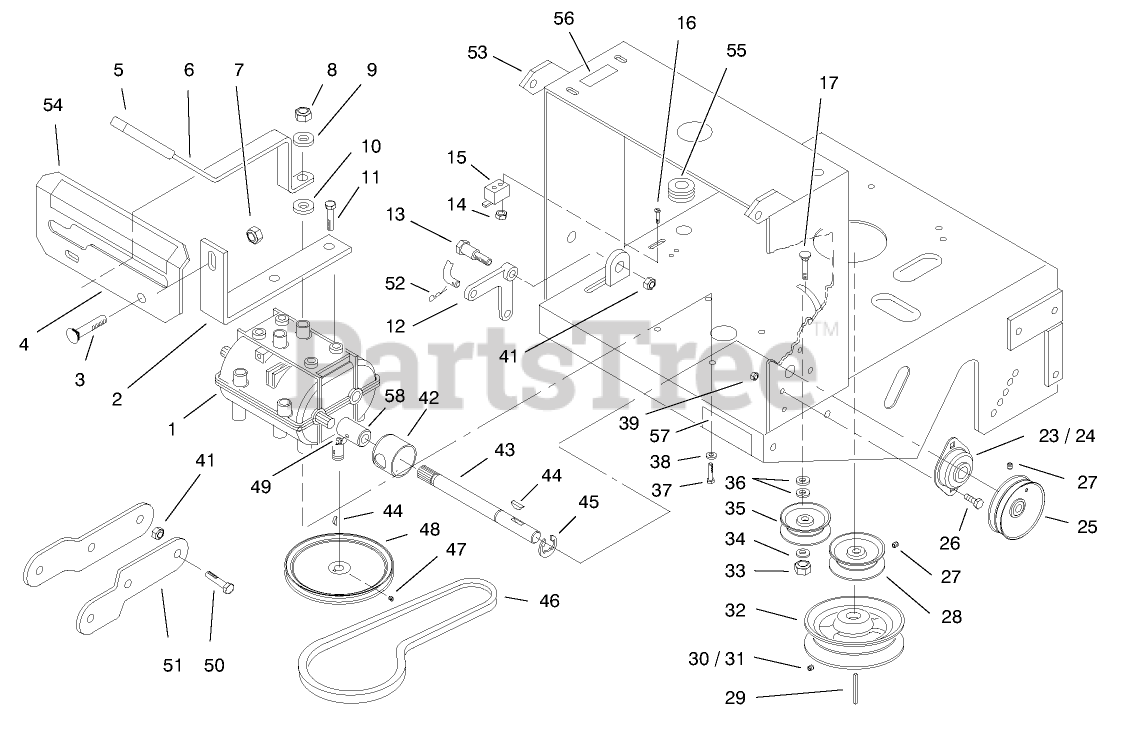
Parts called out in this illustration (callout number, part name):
1	Transmission-Peerless Model No. 700-070a Obtain Parts From Peerless
2	Leg-Shifter Lever
3	BOLT-CARR
4	Shifter Plate
5	Grip
6	Lever-Shift
7	NUT-HF
8	NUT-LOCK
9	Washer
10	Washer
11	SCREW-HWH
12	Bell Crank
13	Bolt-Shoulder
14	Nut
15	Switch-Seat
16	Screw
17	Bolt-CARR
23	Bearing
24	Flange
25	Sheave
26	SCREW-HH
27	Screw-Set
28	Sheave
29	Key
30	SCREW-SET, SQH
31	SCREW-SET, SQH
32	Pulley
33	NUT-HEX
34	WASHER-FLAT
35	Idler Pulley
36	WASHER-FLAT
37	SCREW-HH
38	WASHER-LOCK
39	NUT-LOCK
41	NUT-FLANGE
42	Coupling
43	Output Shaft
44	Key
45	Ring-Retaining
46	Belt-Trans Drive
47	Screw-Set
48	Sheave
49	FITTING-STRAIGHT
50	SCREW-HH
51	Hitch Bracket
52	PIN-COTTER
53	Deck-Engine
54	Decal-Ground Speed
55	Grommet-Fuel Line
56	DECAL-SHUT OFF, FUEL
57	Decal-Caution
58	GUARD-COUPLER
